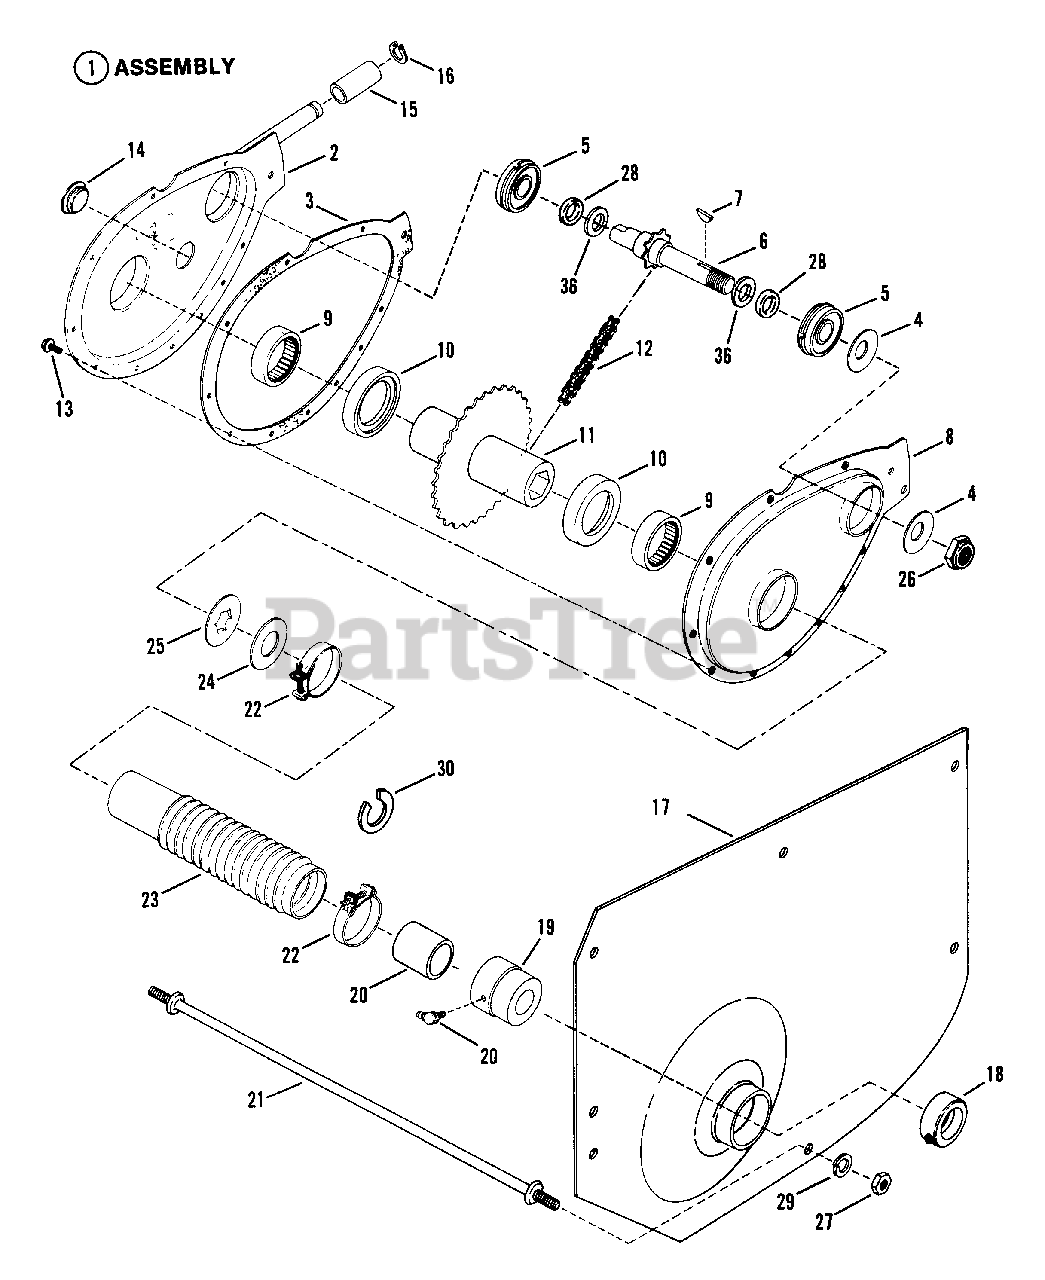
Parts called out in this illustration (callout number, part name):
1	ASSEMBLY, Chain Case
2	CASE, Sprocket
3	GASKET, Case Cover
4	WASHER, Belleville
5	BEARING, Ball
6	SPROCKET & SHAFT
7	KEY, 1/8 x 5/8" Woodruff
8	COVER, Chain Case
9	BEARING, Needle
10	WASHER, Nylon Thrust
11	HUB & SPROCKET
12	CHAIN
13	SCREW, #10-24 x 1/2" Hex Washer Self-Tap (Torx)
14	PLUG, Oil Fill & Check
15	ROLLER
16	RING, Retaining
17	FENDER, Left Hand
18	CAP, Seal L.H. 3/4"
19	BEARING, Left Hand Fender
20	FITTING, Lube
21	ROD, Cross-Tie
22	CLAMP, Boot
23	BOOT, Oil Seal
24	WASHER, Thrust Nylon
25	WASHER, Thrust
26	NUT, 5/8-18 Hex Lock
27	NUT, 5/16-24 Hex
28	O-RING
29	WASHER, 5/16 Split Lock
30	WASHER, Shim
36	WASHER, Shim
